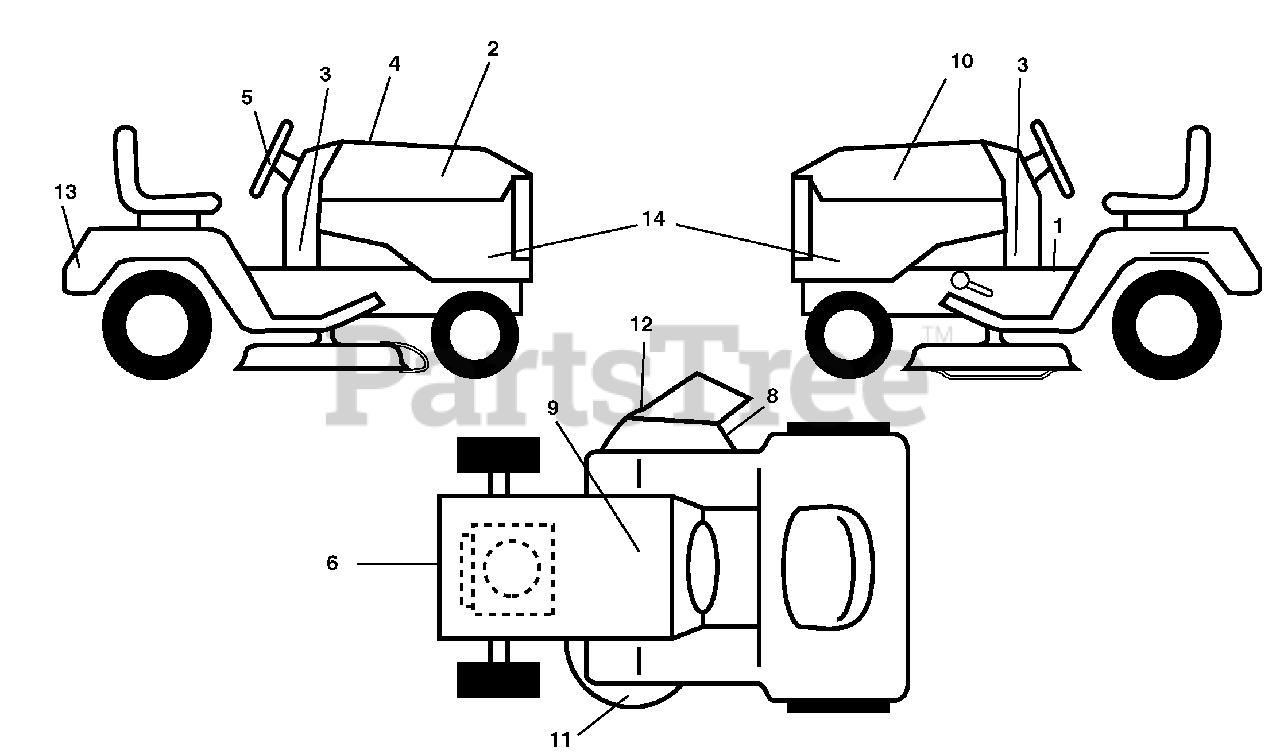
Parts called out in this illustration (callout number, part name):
1	Decal, Operator's
2	Decal, Hood RH
3	Decal, Chassis
4	Decal, Replacement
5	Decal, Strg Whl
6	Decal, Engine HP
8	Decal, Mower Sch.
9	Decal, Battery Dnge/Poi
10	Decal, Hood LH
11	Decal, Mower Caution
12	Decal, Mower Warning Keep Hand Away
13	Decal, Fender
14	Decal, Panel SD
14	Decal, Bypass
14	Pad, Footrest, LH
14	Pad, Footrest, RH
14	Manual, Operator's (Eng & French)
14	Manual, Parts
